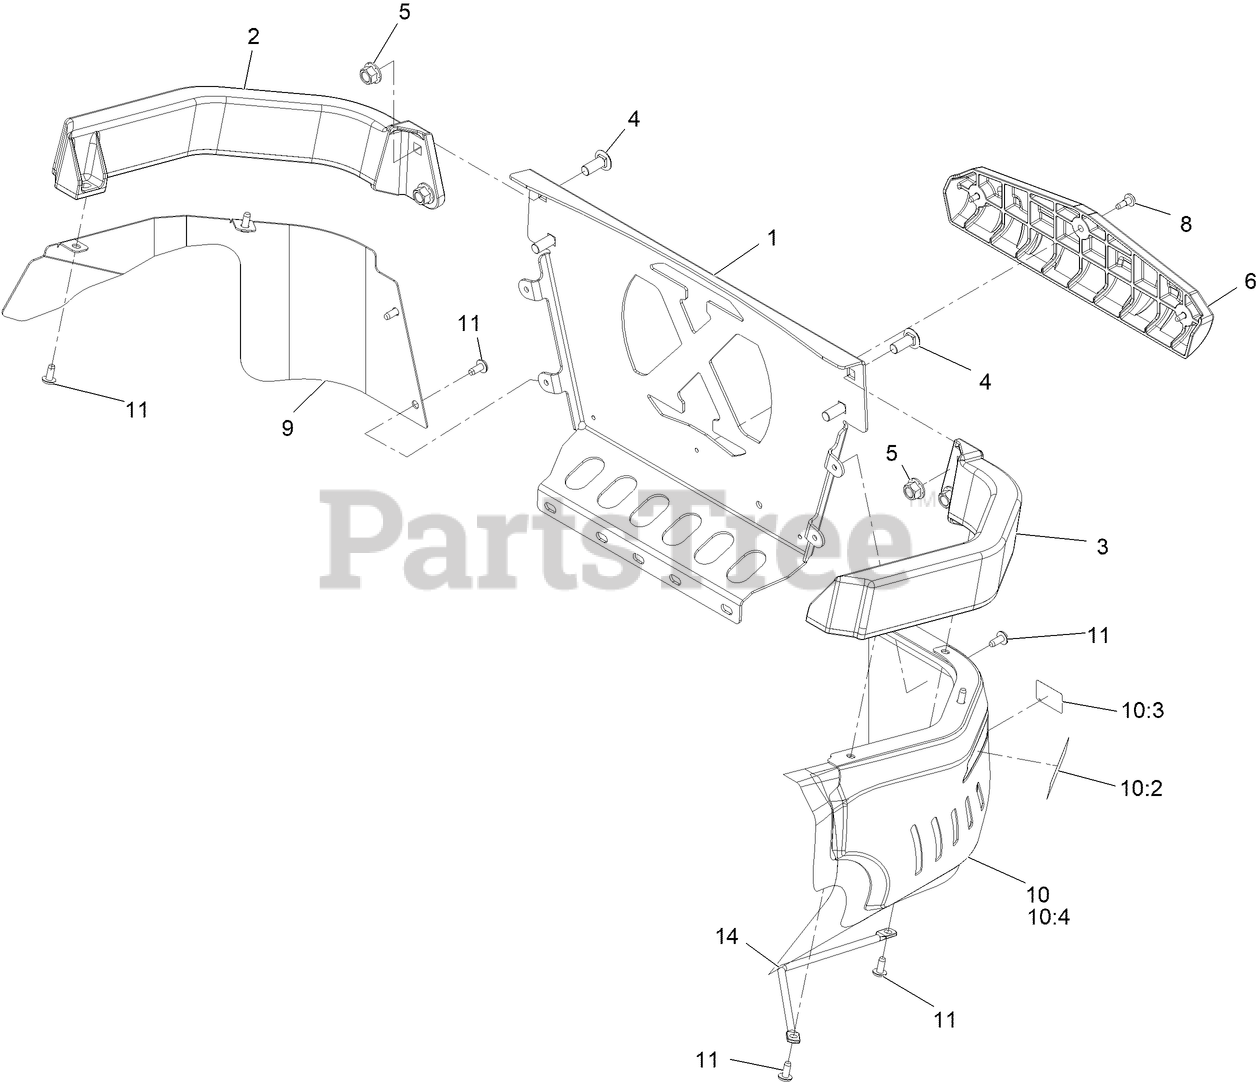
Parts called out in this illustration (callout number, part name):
1	PLATE-REAR
2	SIDE-CAGE, RT
3	SIDE-CAGE, LT
4	SCREW-CARR, SHORT NECK
5	Nut-Lock 1/2-13
6	BUMPER-REAR
8	SCREW-SHOULDER
9	Panel-Quarter RH
10	PANEL-QUARTER, LH ASM
10:2	DECAL-X-SERIES
10:3	DECAL-WARNING
10:4	SHIELD-QUARTER PANEL, LT
14	GUARD-MUFFLER WIREFORM
